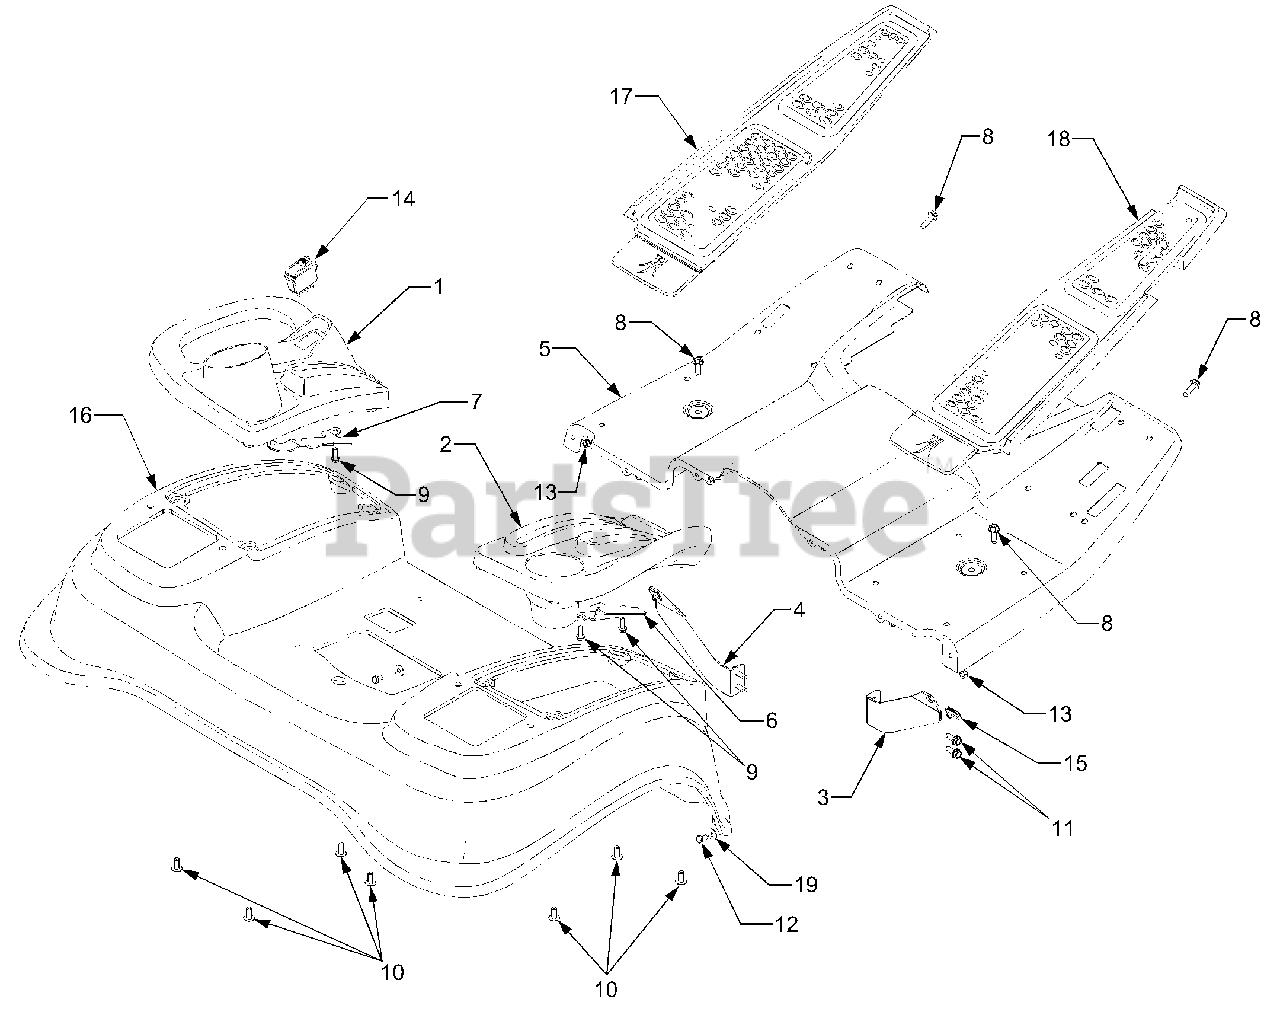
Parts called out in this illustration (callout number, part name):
1	Cover, Fender, LH
2	Cover, Fender, RH
3	Bracket, Running Board Mtg. RH
4	Bracket, Running Board Mtg. LH
5	Running Board
9	Screw, Hex Wash. Hd, Tapp 1/4-15 x .75
10	Screw, Truss Phillips Hd. 5/16-14 x .75
11	Screw, Hex Wash. Hd. Tapp 5/16-18 x .75
12	Screw, Hex Cap, 1/4-20 x .5 GR5
13	Nut, Hex Insert Lock, 1/4-20 GR8
14	Switch, PTO Reverse
15	Nut, Speed, 5/16-18
16	Fender
17	Pad, Floor - LH
18	Pad, Floor - RH
19	Washer, Flat, .26 x .72 x .06
